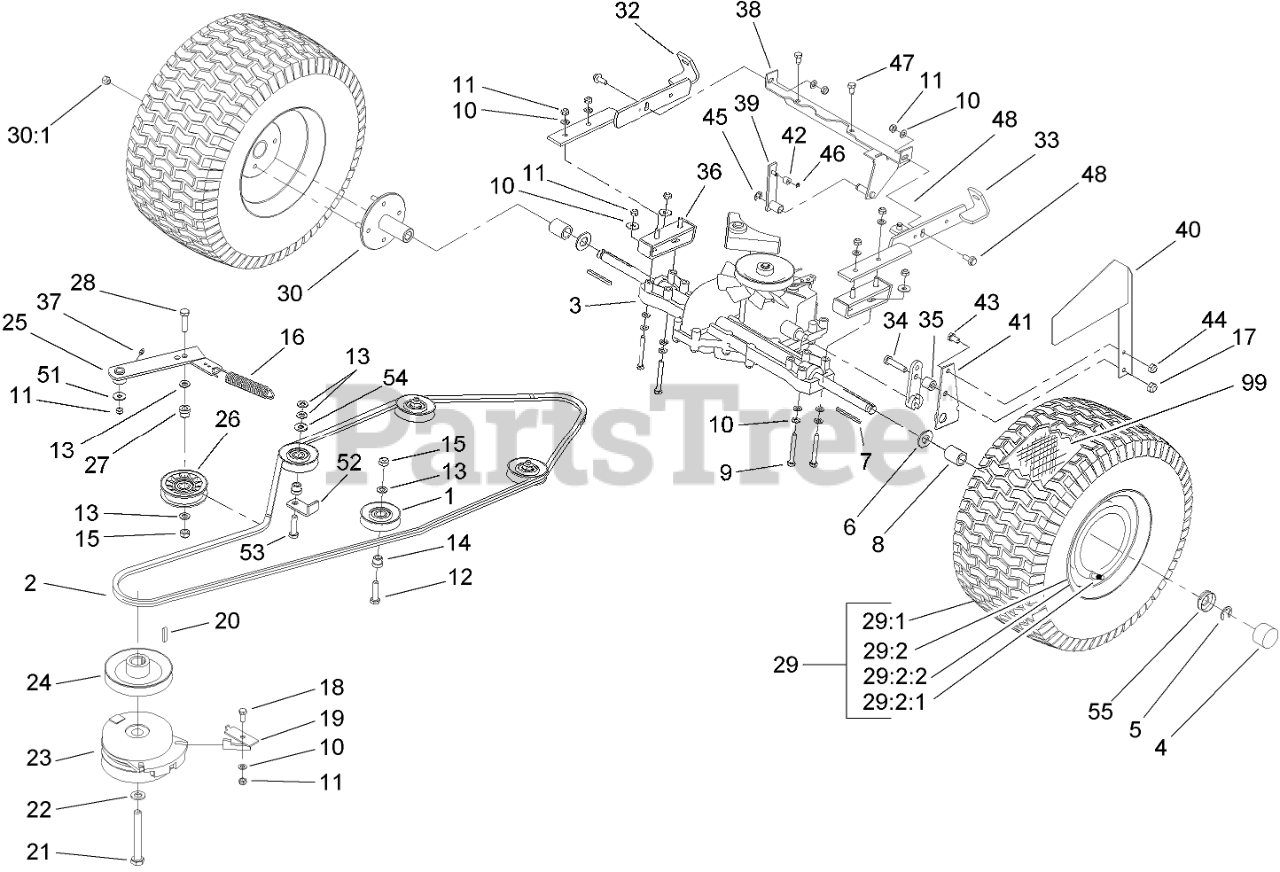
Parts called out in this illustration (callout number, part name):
1	PULLEY-IDLER
2	V-BELT-TRACTION
3	TRANSMISSION
4	CAP-HUB
5	CLIP-SPRING
6	WASHER
7	KEY-SQUARE
8	SPACER-AXLE
9	SCREW-HH
10	WASHER-PLAIN
11	NUT-LOCK, NI
12	SCREW-HH
13	WASHER-FLAT
14	BUSHING-IDLER
15	NUT-LOCK, NI
16	SPRING
17	NUT-LOCK, NI
18	SCREW-HH
19	RETAINER
20	KEY-SQUARE
21	SCREW-HH
22	WASHER-SPRING, BELLEVILLE
23	CLUTCH-ELECTRIC
24	PULLEY-ENGINE
25	ARM-IDLER
26	PULLEY-IDLER
27	BUSHING-IDLER
28	SCREW-HH
29	TIRE AND WHEEL ASM
29:2	WHEEL ASM
29:2:1	RIM
29:2:2	Valve-Tire
30:1	NUT-LUG
32	Bracket-Right
33	Bracket-Left
34	SCREW-HH
35	SLEEVE
36	Plate-Reinforcing
37	FITTING-GREASE
38	Bar ASM
39	Arm-Switch
40	ARM-CONTROL, CRUISE
42	Roller
43	SCREW-HH
44	NUT-LOCK, NI
45	Stirrup
46	STIRRUP
47	SCREW-THREAD FORMING
48	SCREW-HEX
51	WASHER-PLAIN
52	RETAINER-BELT
53	SCREW-HH
54	WASHER-FLAT
55	RETAINER-CAP, HUB
